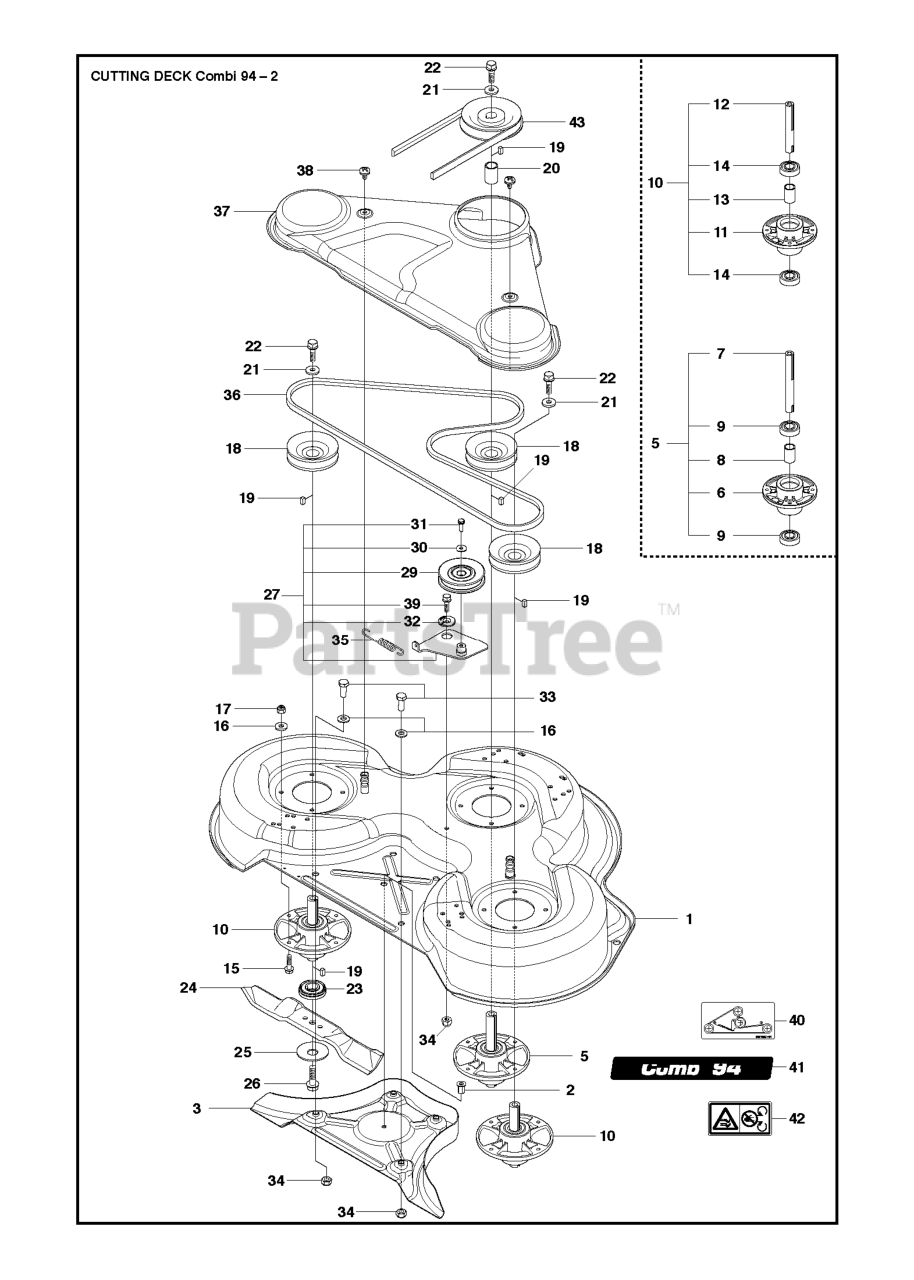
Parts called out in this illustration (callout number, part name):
3	PLUG C93 & C94
5	BLADE HOUSING ASSY
6	BEARING HOUSING
8	SPACING SLEEVE
10	BLADE HOUSING ASSY
11	BEARING HOUSING
13	SPACING SLEEVE
16	WASHER BRB 8.4X17
17	LOCKNUT M8
27	BELT TENSIONER ASSY KIT
32	WASHER SHOULDER ASSY
34	LOCKNUT M8
37	BELT COVER C93 & C94 GREY
